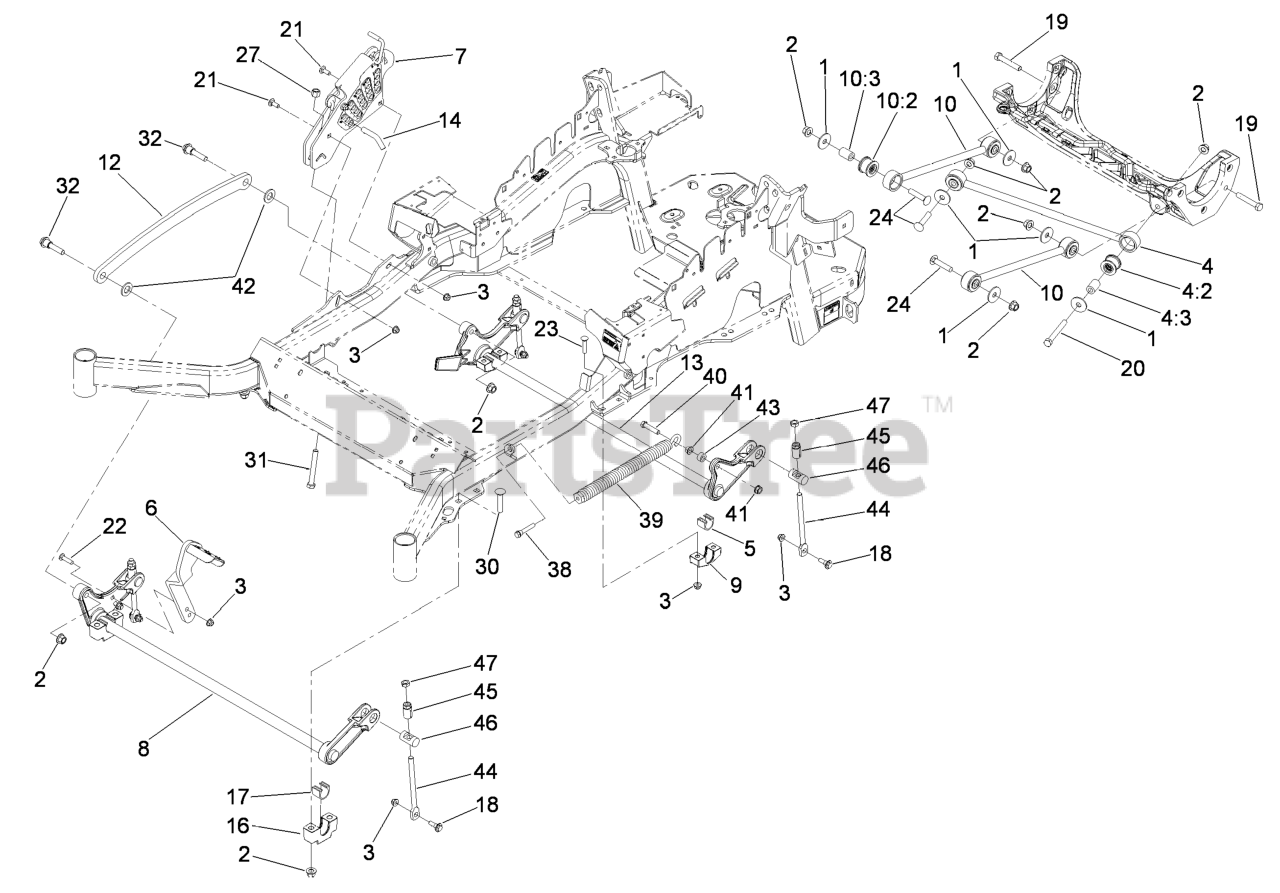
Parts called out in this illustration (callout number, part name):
1	WASHER-THRUST
2	Nut-Lock 1/2-13
3	NUT-HF, NI
4	PANHARD ROD ASM
4:2	BUSHING-SUSPENSION, RUBBER
5	BEARING-CROSS SHAFT, REAR
6	LEVER-FOOT
7	HOC ASM
10	DECK STRUT ASM
10:2	BUSHING-SUSPENSION, RUBBER
12	LINK-LIFT, DECK
13	LIFT-DECK, REAR
14	PIN-HOC
16	SUPPORT-CROSS SHAFT, BEARING
17	BEARING-CROSS SHAFT, FRON
18	SCREW-SHOULDER, HHF
19	SCREW-HH
20	SCREW-HH
21	BOLT-CARR
22	SCREW-CARR
23	SCREW-CARR
24	SCREW-CARR
27	NUT-LOCK, NI
30	Bolt-Carriage 1/2-13 X 2 1/2 Spl Neck
31	BOLT-TAP
32	SCREW-HHF, SHOULDER
38	BOLT-SHOULDER
39	SPRING-EXTENSION
40	SCREW-HH
42	WASHER-FLAT
44	LINK-ADJUSTER, DECK LIFT
45	ADJUSTER-LIFT, DECK
46	TRUNNION
47	NUT-JAM
